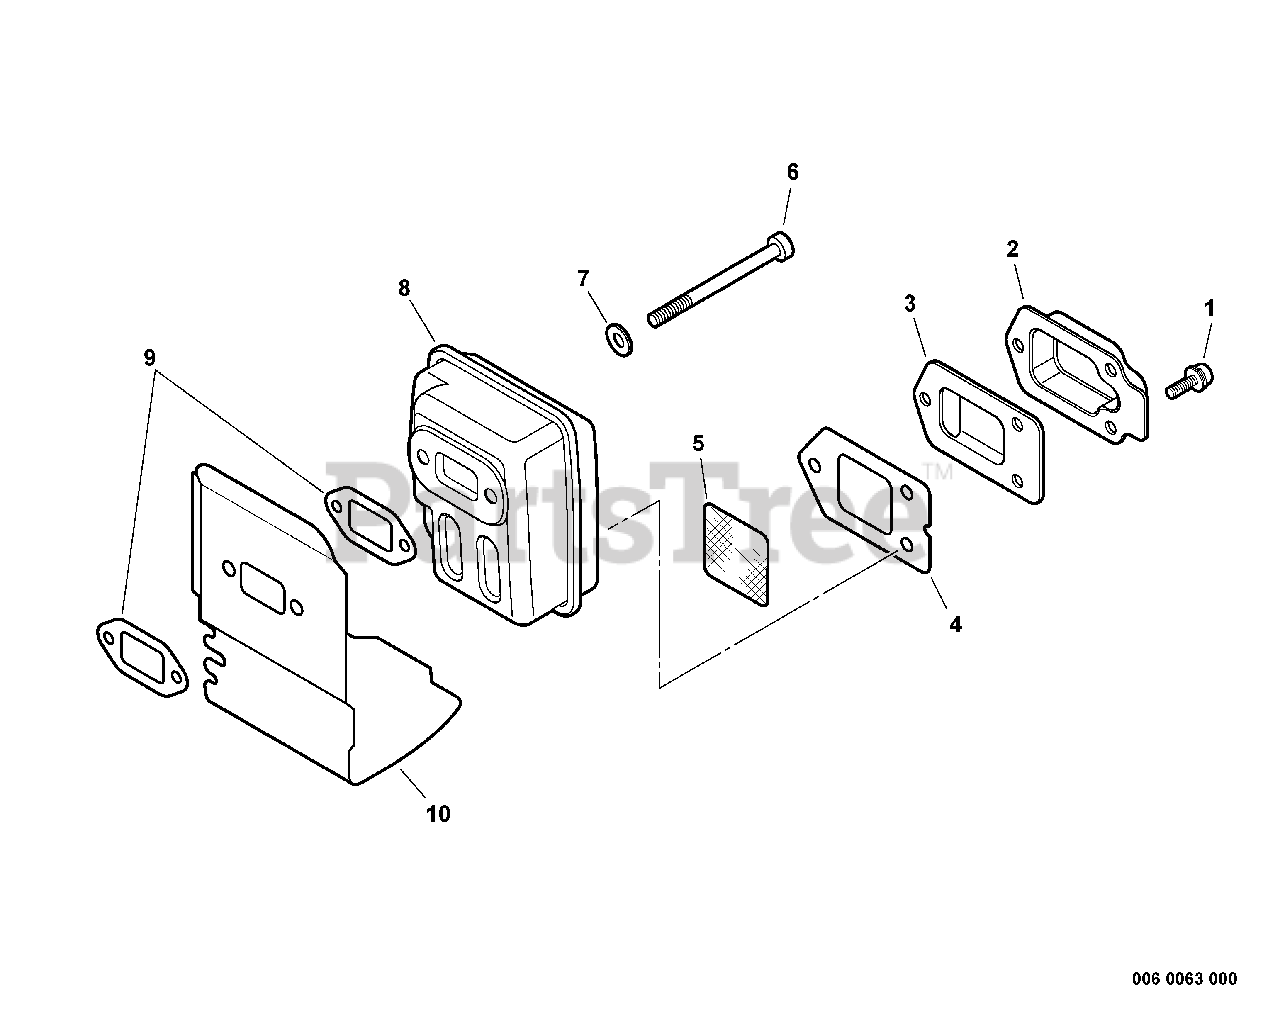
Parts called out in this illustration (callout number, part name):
1	SCREW 4×10
2	GUIDE, EXHAUST - INNER
3	GUIDE, EXHAUST
4	GASKET, EXHAUST
5	SCREEN, SPARK ARRESTER
6	BOLT 5×55
7	WASHER 5.5×12×0.8
9	GASKET, EXHAUST
10	COVER, MUFFLER
